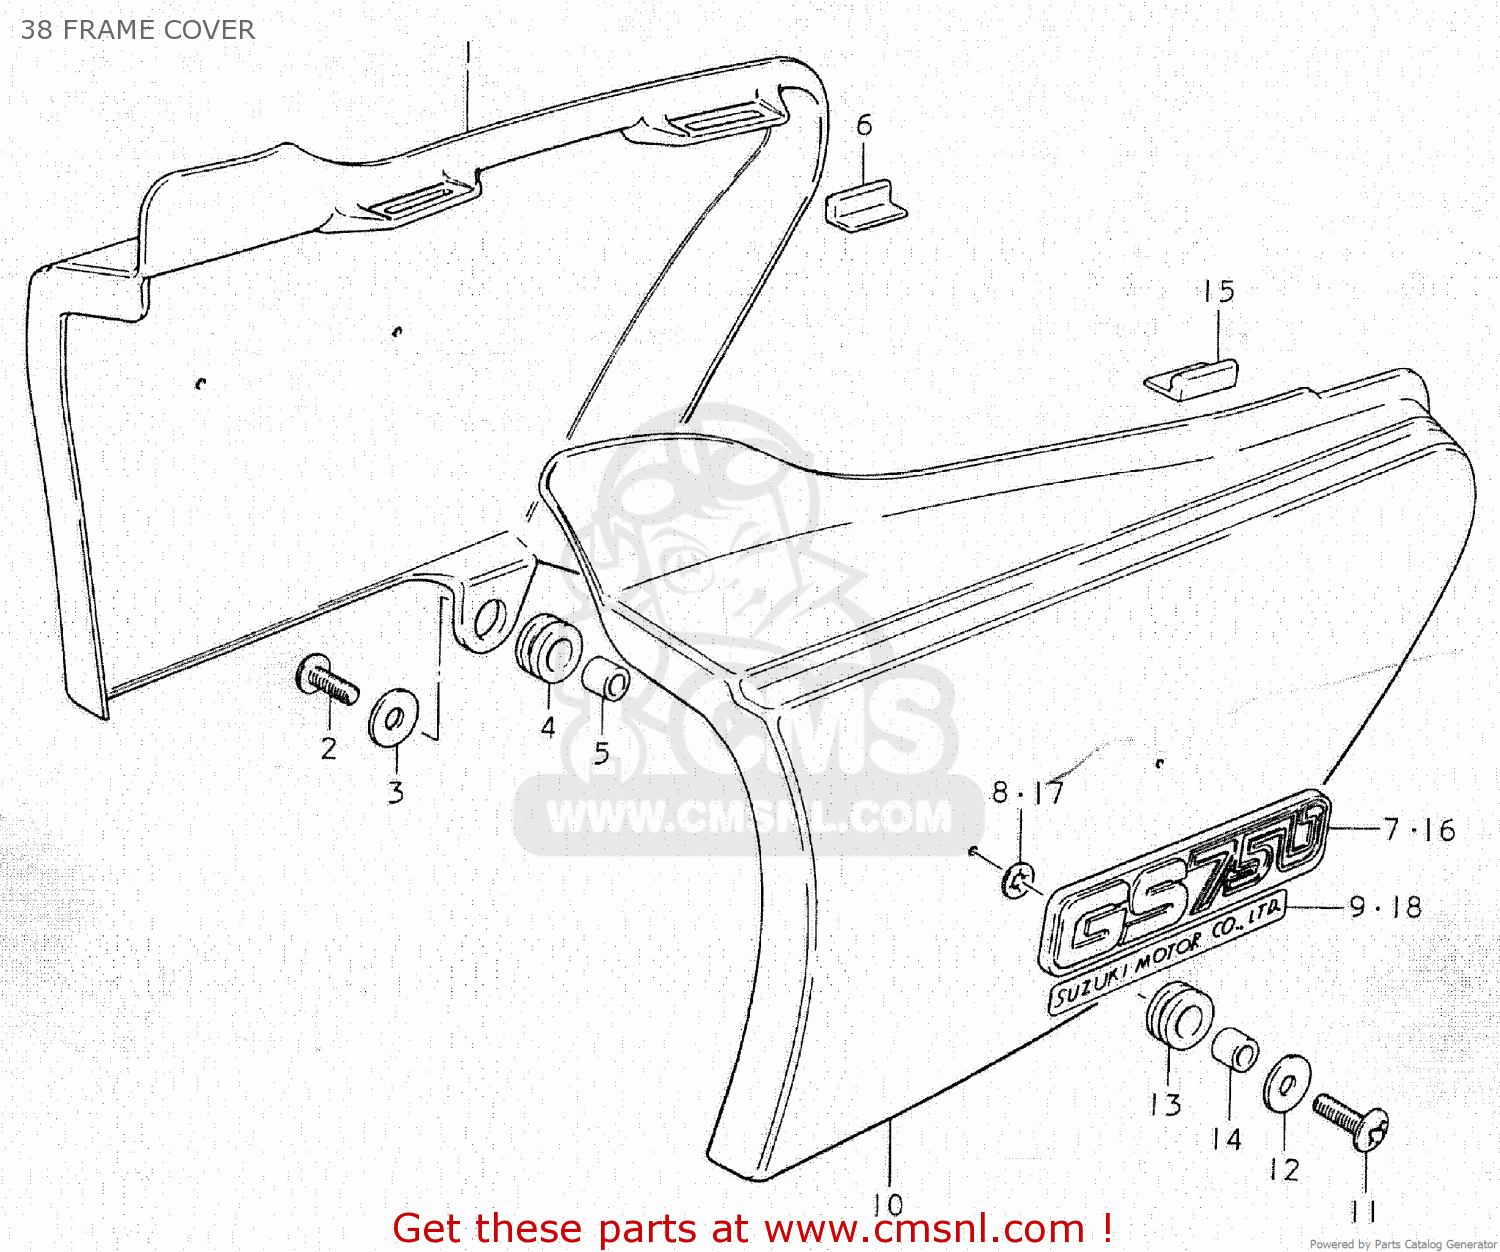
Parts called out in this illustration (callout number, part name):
1	COVER,FRAME,RIGHT
2	SCREW (6X20)
3	WASHER (6.5X18X1.6)
4	CUSHION
5	SPACER (6.8X10X10)
6	CUSHION,FRAME COVER
7	EMBLEM,FRAME COVER
8	NUT
9	LABEL,COMPANY NAME
10	COVER,FRAME,LEFT
11	SCREW (6X20)
12	WASHER (6.5X18X1.6)
13	CUSHION
14	SPACER (6.8X10X10)
15	CUSHION,FRAME COVER
16	EMBLEM,FRAME COVER
17	NUT
18	LABEL,COMPANY NAME
